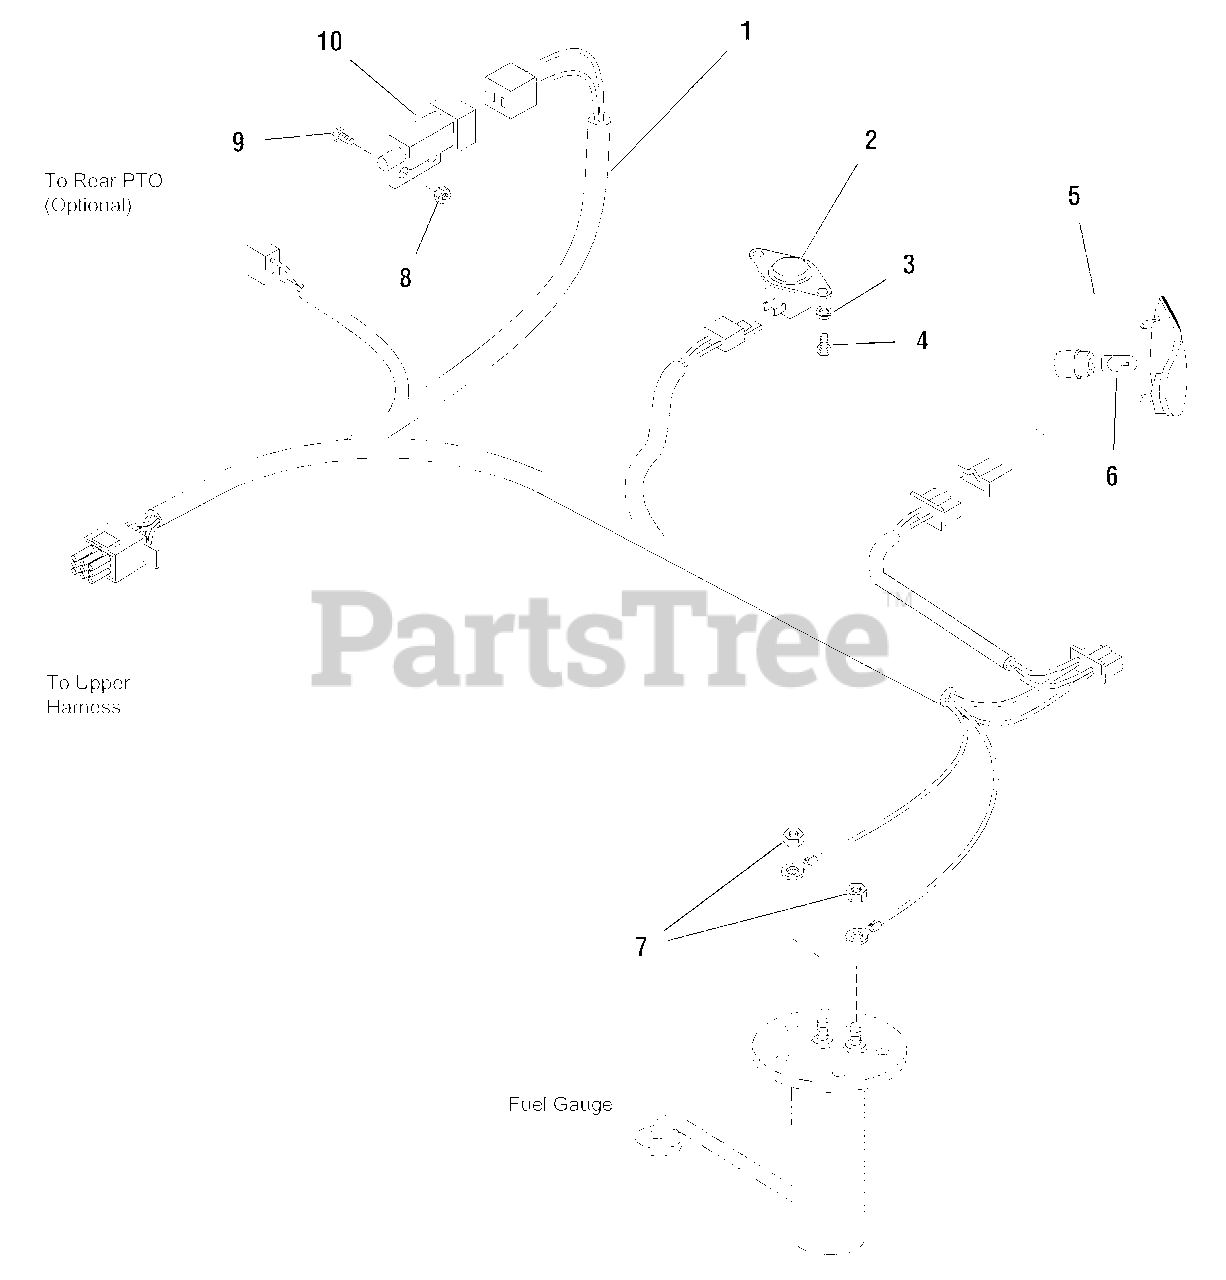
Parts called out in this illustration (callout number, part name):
1	HARNESS, Rear
2	SWITCH, Seat
3	LOCKWASHER, 1/4
4	CAPSCREW, Hex Hd, 1/4-20 x 3/4
5	TAIL LIGHT, Assembly
6	BULB, Tail Light
7	NUT, Hex Flange, #10-32
8	NUT, Hex Lock, #10-24
9	CAPSCREW, #10-24 x 5/8
10	SWITCH, Cruise Control
